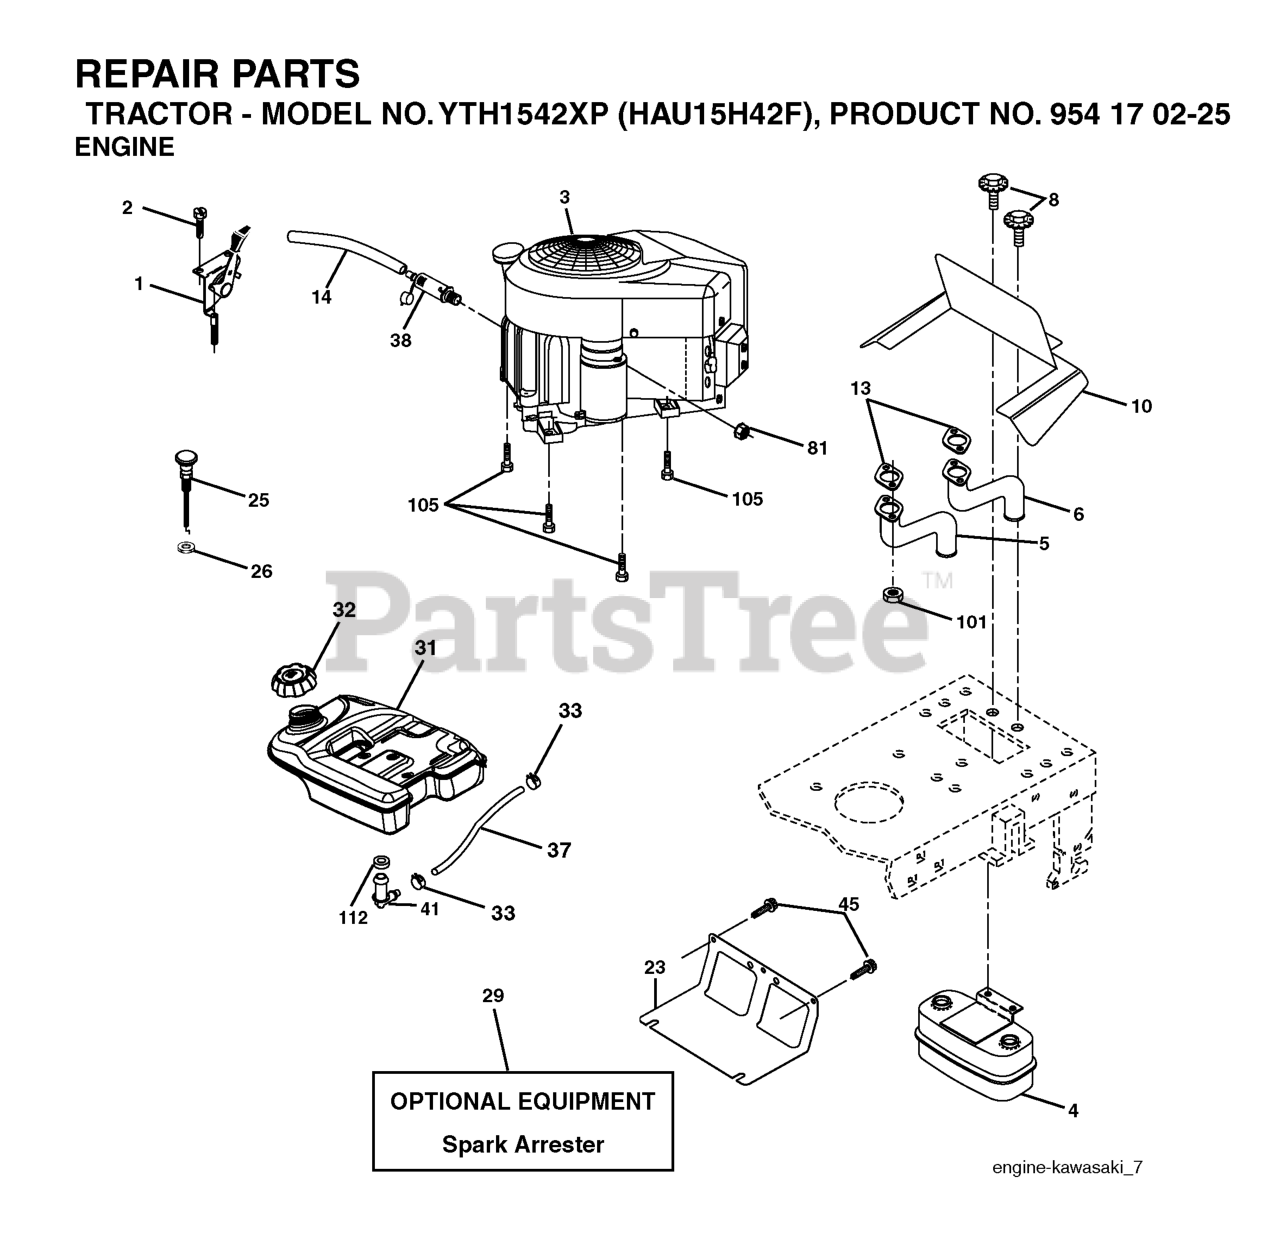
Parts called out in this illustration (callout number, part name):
1	THROTTLE CABLE
2	SCREW
4	MUFFLER.TWIN.CYL.LOW.TONE
5	EXHAUST TUBE LH KAWI
6	EXHAUST TUBE RH KAWI
8	BOLT.5/16-18UNCX3/4 W/SEMS.BLK
10	RP SHIELD HEAT MUFFLER
14	TUBE, DRAIN OIL ASM.
23	SHIELD.BROWNING.DBR.GUARD
25	REPL BY 532 1754-40
26	Nut Keps 3/8 - 24 UNF
29	KIT.SPARK ARRESTOR 794945 B&S
31	4.0 REAR FUEL TANK
32	TANK CAP
33	HOSE CLAMP
37	REPL BY 532 00 85-43
41	STEM FUEL TANK
45	SCREW, 3/8-16X3/4
81	NUT
101	NUT.HEX.FLANGE.TOPLOCK
105	SCREW 3/8-16X1
112	BUSHING OUTLET T
